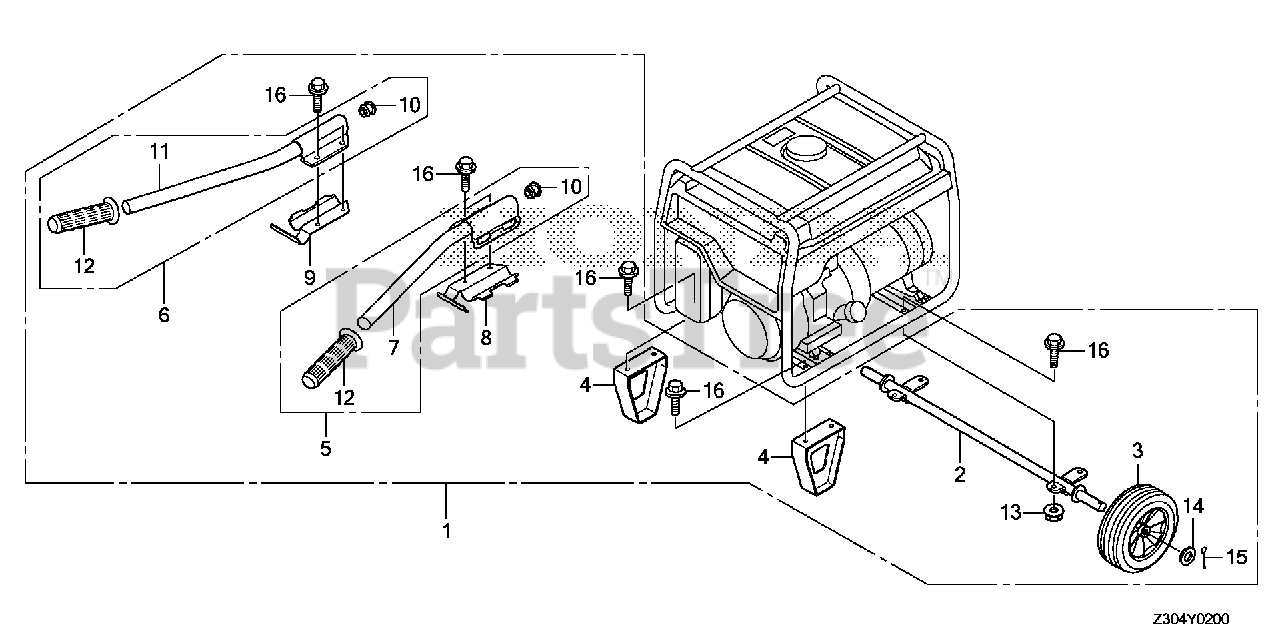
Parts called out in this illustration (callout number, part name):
1	WHEEL KIT (2-WHEELS) *NH105* (MAT BLACK)
2	SHAFT, WHEEL *NH105* (MAT BLACK)
3	WHEEL (254X63.5) (COO)(FOR U.S.A.)
4	STAND *NH105* (MAT BLACK)
5	HANDLE ASSY., R. (UPPER) *NH105* (MAT BLACK)
6	HANDLE ASSY., L. (UPPER) *NH105* (MAT BLACK)
7	HANDLE, R. (UPPER) *NH105* (MAT BLACK)
8	BRACKET, R. HANDLE (LOWER) *NH105* (MAT BLACK)
9	BRACKET, L. HANDLE (LOWER) *NH105* (MAT BLACK)
10	CAP, HANDLE (LOWER)
11	HANDLE, L. (UPPER) *NH105* (MAT BLACK)
12	GRIP, HANDLE
13	NUT, FLANGE (8MM)
14	WASHER, PLAIN (20MM)
15	PIN, SPLIT (4.0X28)
15	PIN, SPLIT (4.0X30)
16	BOLT, FLANGE (8X16)
